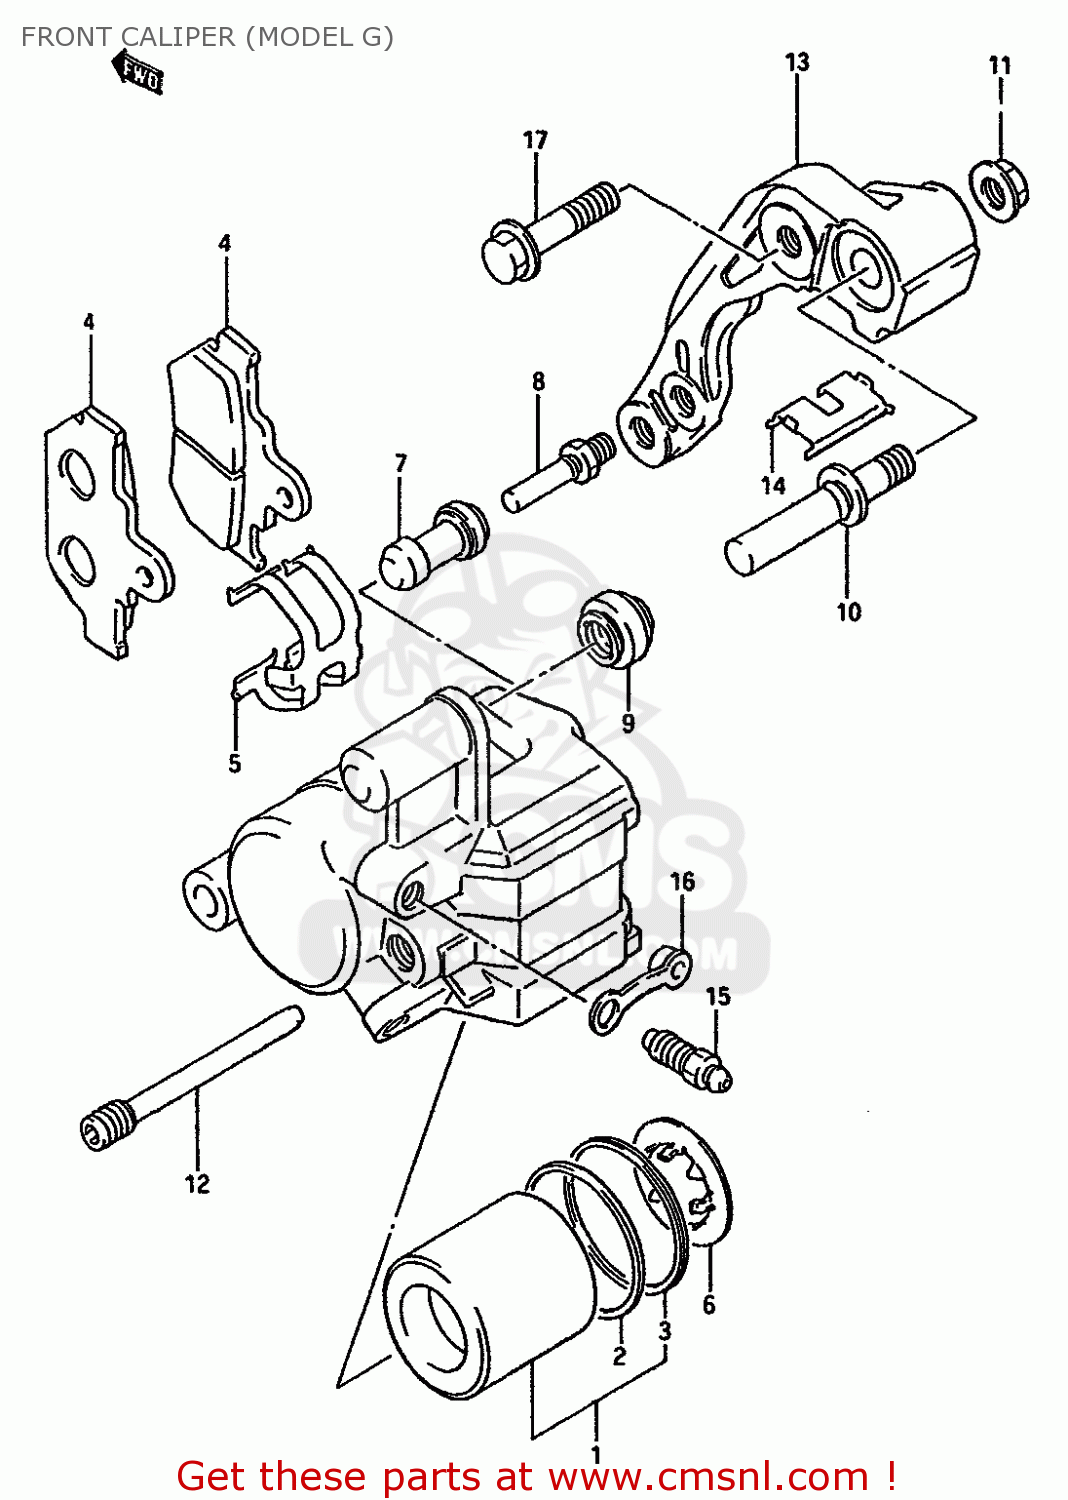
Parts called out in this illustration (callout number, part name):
1	PISTON SET,CALIPERS
2	SEAL,PISTON
3	DUST SEAL,PISTON
4	PAD
5	SPRING
6	SHIM
7	BOOT
8	PIN,BOLT
9	BOOT
10	PIN,SLIDE
11	NUT,SLIDE PIN
12	PIN,HANGER
13	BRACKET
14	RETAINER
15	BLEEDER
16	CAP,BLEEDER
17	BOLT
